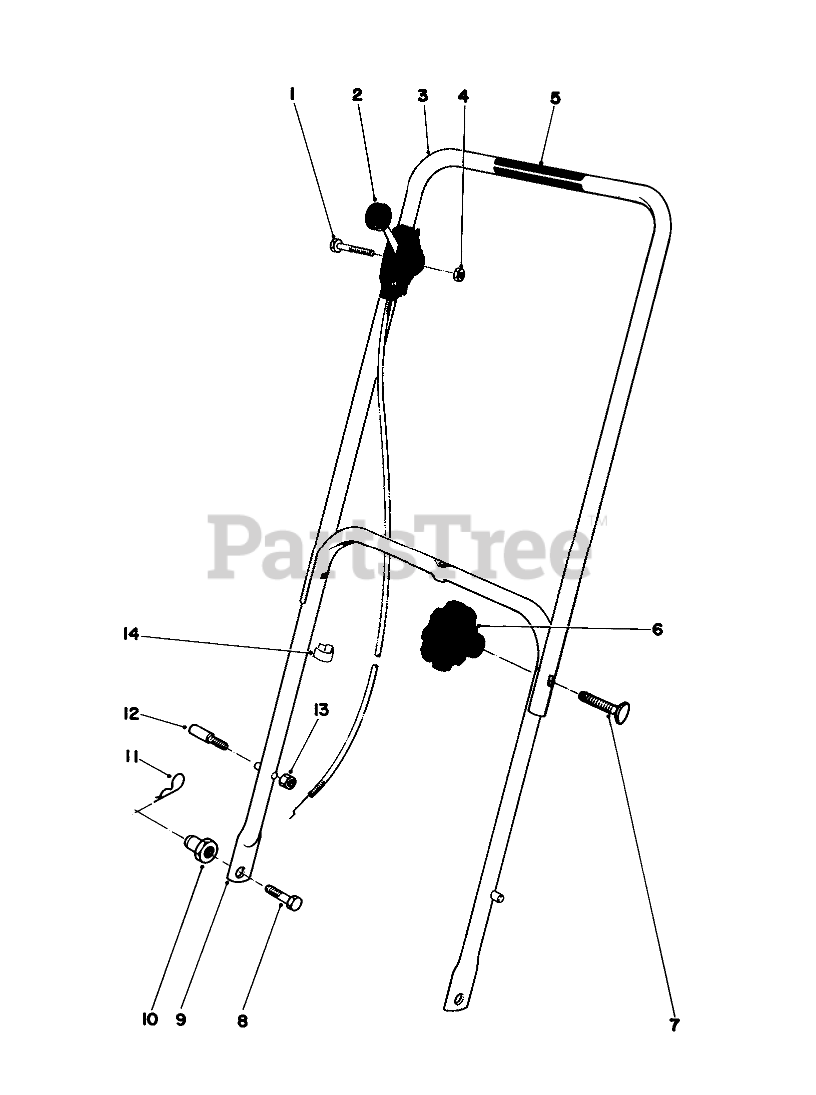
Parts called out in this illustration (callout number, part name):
1	SCREW-HH
2	SERVICE THROTTLE CONTRO
3	Handle-Upper (Inc. Ref. #5)
4	NUT-LOCK
5	Decal-Danger
7	5/16-18 X 2 HNDLE SCREW
8	SCREW-HH
9	Lower Handle
10	HANDLE PIVOT NUT
11	PIN-COTTER, HAIR
12	HANDLE PIN
13	Nut
